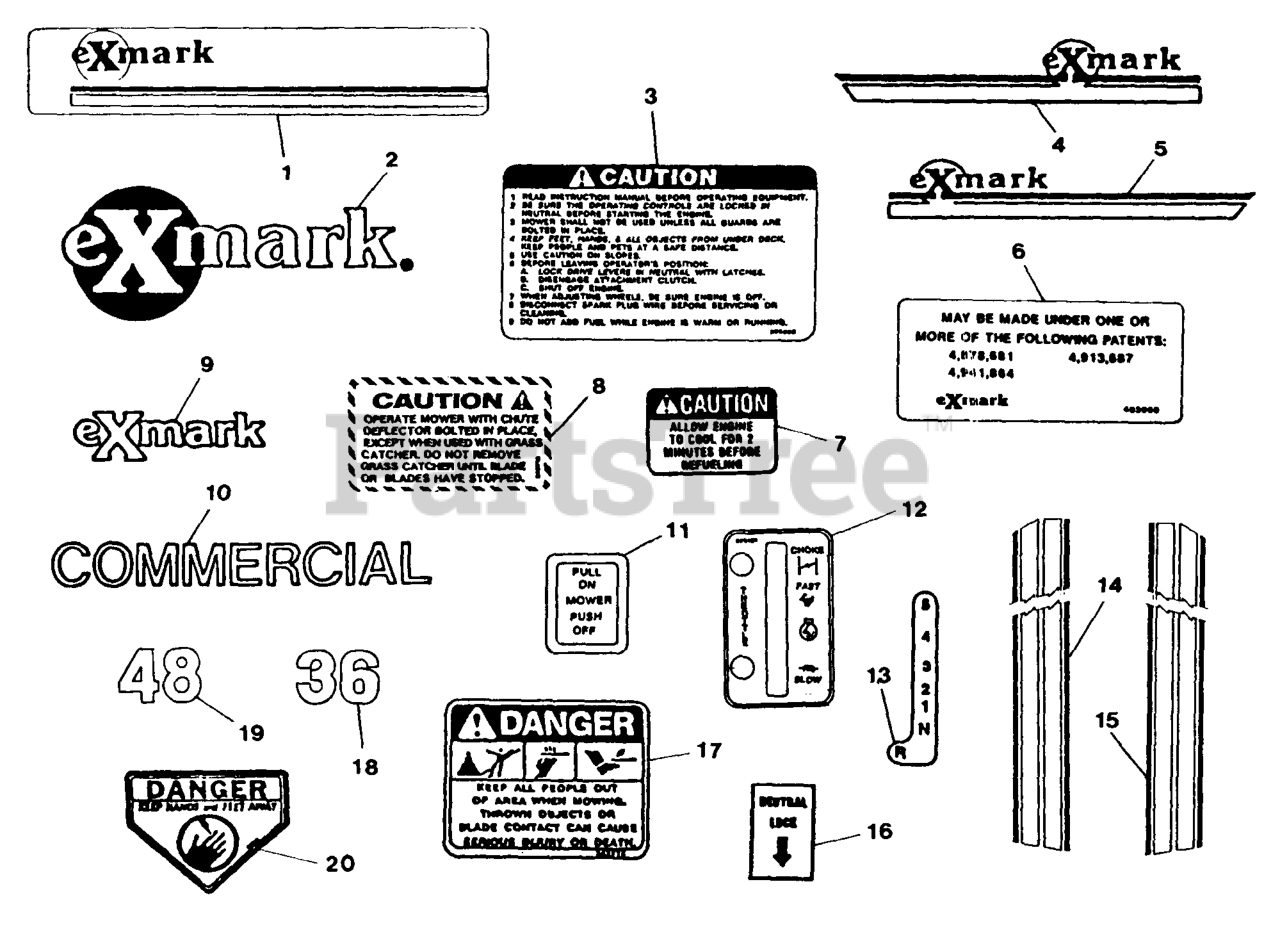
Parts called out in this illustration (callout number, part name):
3	LABEL,INSTRUCTION
16	DECAL,NEUTRAL LOCK
17	DECAL-DANGER
20	DECAL-DANGER
